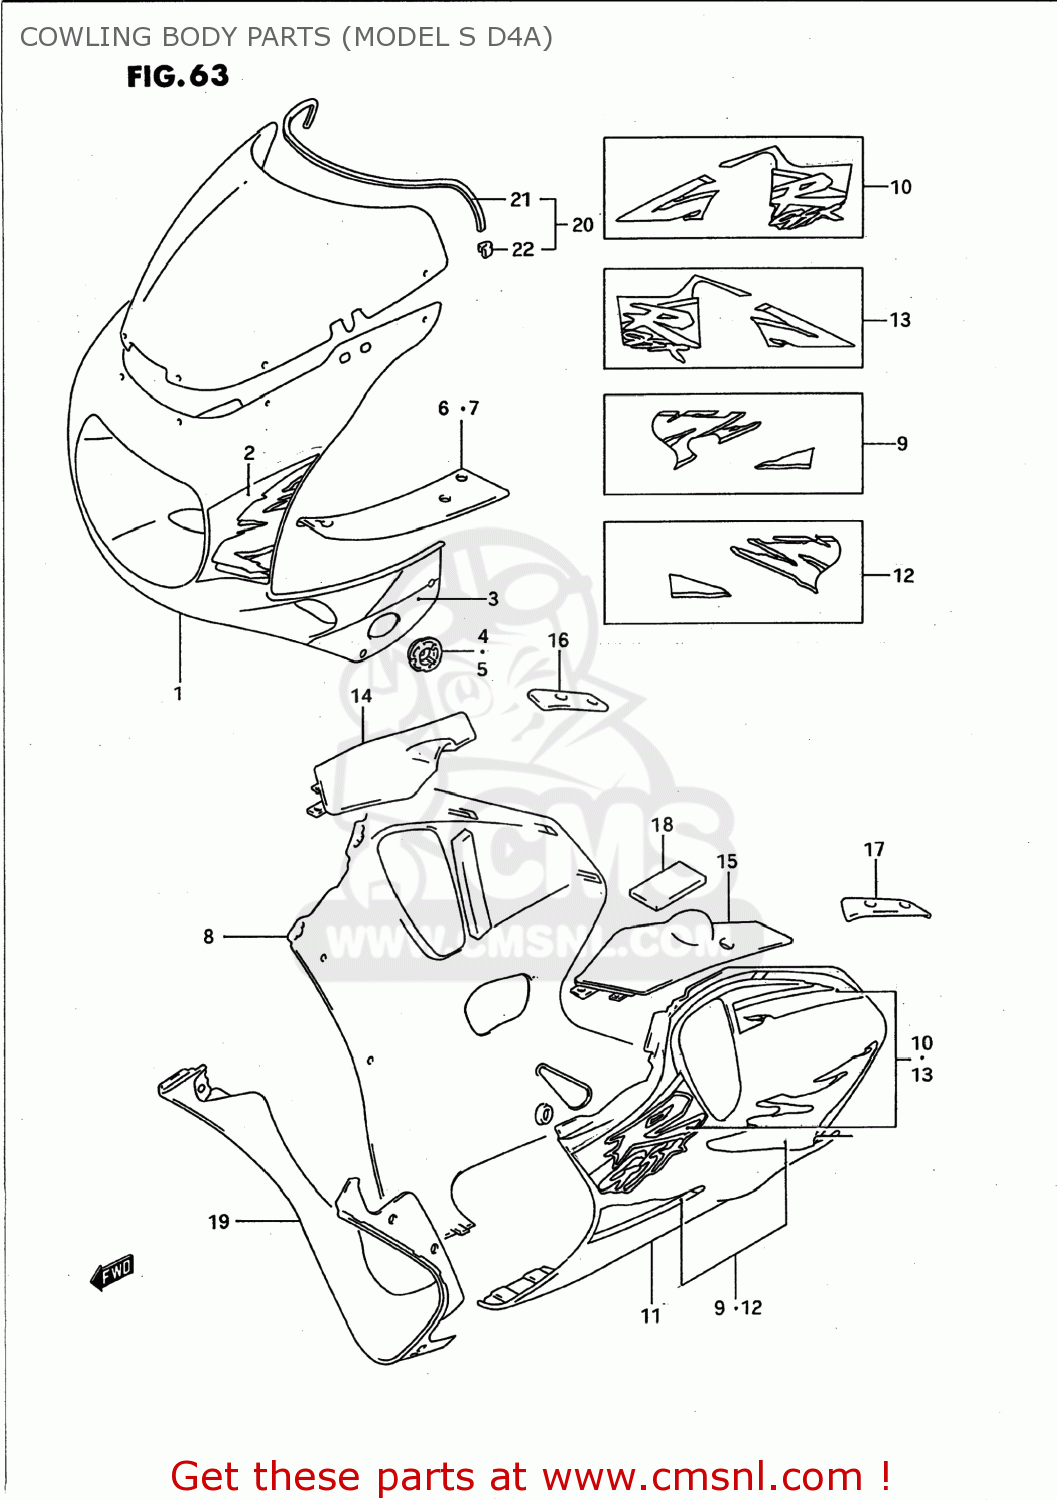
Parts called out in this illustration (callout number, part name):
1	COWLING ASSEMBLY,BODY
2	TAPE SET,COWL BODY FR
3	TAPE SET,COWL BODY SIDE
4	PLATE,TURN SIGNAL,RIGHT
5	PLATE,TURN SIGNAL,LEFT
6	PANEL,COWLING,UPPER,RIGHT
7	PANEL,UPPER,LEFT
8	COWLING ASSEMBLY,UNDER,RIGHT
9	TAPE SET,COWLING,UNDER,LOWER
10	TAPE SET,COWLING,UNDER
11	COWLING ASSEMBLY,UNDER,LEFT
12	TAPE SET,COWLING,UNDER,LOWER
13	TAPE SET,COWLING,UNDER
14	PANEL,LWR FR,R
15	PANEL,LWR FR,L
16	PANEL,LWR RR,R
17	PANEL,LWR RR,L
18	CUSHION,PANEL
19	COWLING,UNDER CTR
20	SCREEN SET,WINDOW
21	MOLDING WINDSCREEN
22	CLIP,WINDSCREEN MOLDING
